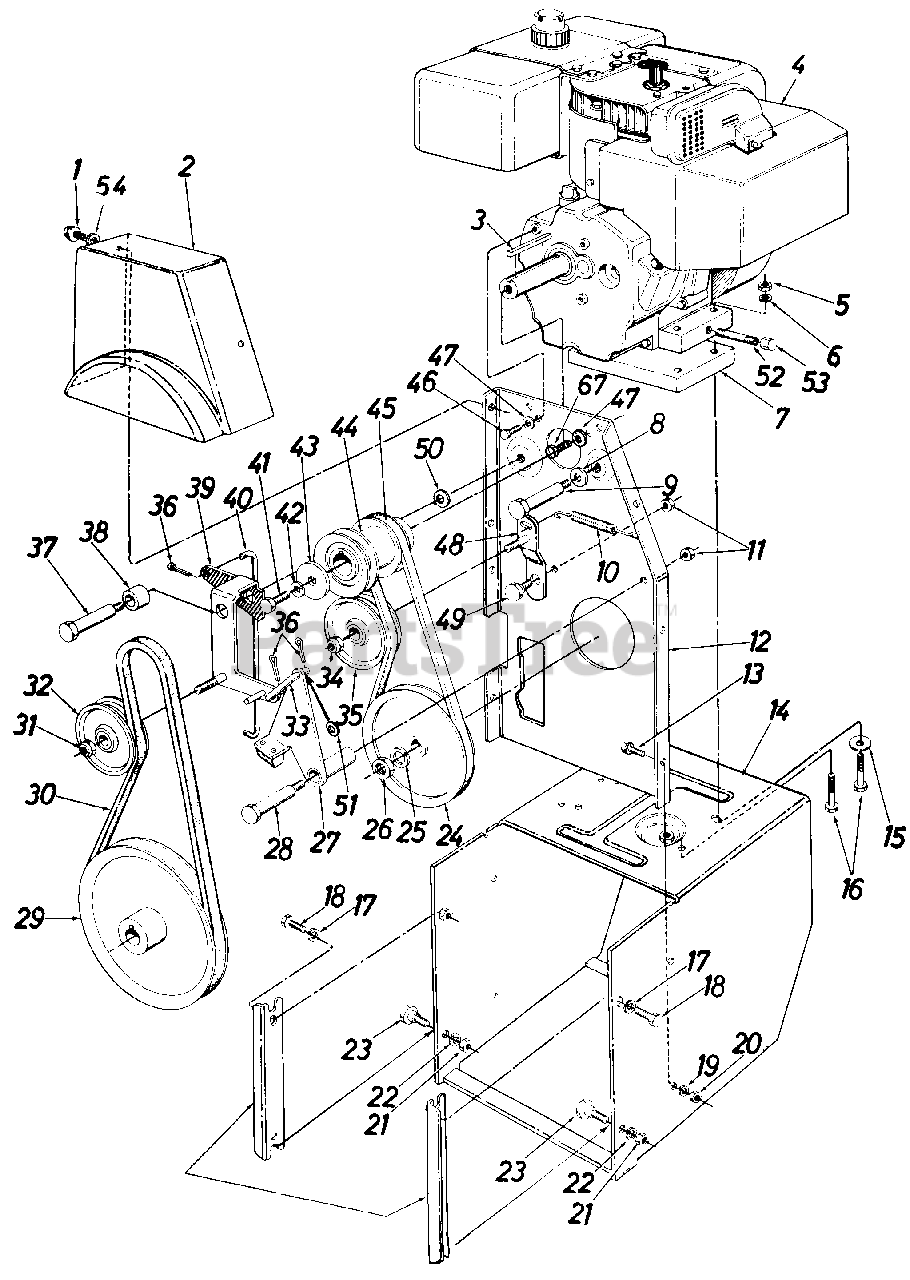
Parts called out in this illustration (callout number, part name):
1	Hex Wash. Self-Tap Scr. 5/16-24 x .50" Lg.
2	Belt Cover
3	Sq. Key 1/4" x 1.50" Lg.
4	Engine
5	Hex Nut 5/16-18 Thd.
6	L-Wash. 5/16" Scr.
7	Engine Spacer Ass'y.
8	Bell-Wash. .40 I.D. x .88 0. D
9	Shld. Scr. .498" Dia. x 3.00" Lg.
10	Ext Spring .38 O.D. x 3.18" Lg.
11	Hex Cent. L-Nut 3/8-16 Thd.
12	Engine Brkt. Ass'y.
13	Hex Sems Scr. 5/16-18 x .75" Lg.
14	Frame Ass'y.
15	Fl-Wash. .345 I.D. x .75 O.D. x .060
16	Hex Scr. 5/16-18 x 2.50" Lg.
17	L-Wash. 3/8" Scr. H.D.
18	Pilot Scr. 3/8-16 x .88" Lg.
19	L-Wash. 5/16" Scr.
20	Hex Nut 5/16-18 Thd.
21	Hex Nut 3/8-16 Thd.*
22	L-Wash. 3/8" Scr. H.D.
23	Shld. Scr. .498" Dia. x .340" Lg.
24	V-Puiley .628 I.D. x 7.50 O.D.
25	L-Wash. for 5/8" Scr.
26	Hex Ins. Jam L-Nut 5/8-18 Thd.
27	Brake Brkt. Ass'y.
28	Shld. Scr. .498" Dia. x 2.00" Lg.
29	V-Pulley .875 I.D. x 10.12 O.D.
30	"V"-Belt
31	Hex Ins. Jam L-Nut 3/8-24 Thd.
32	Fl-Idler w/Flanges 3.0 O.D.
33	Brake Linkage Ass'y.
34	Hex Ins. Jam L-Nut 3/8-24 Thd.
35	3.0" O.D. Fl-Idler w/Flanges
36	Int. Cot. Pin 5/16" Dia.
37	Shld. Scr. .625 Dia. x 2.750" Lg.
38	Spacer .75 O.D. x 1.00" Lg.
41	Hex Bolt 3/8-24 x 1.25" Lg.
42	L-Wash. 3/8" Scr. H.D.
43	Fl-Wash.
44	Engine Pulley-Double Groove
45	"V"-Belt
46	Hex Scr. 5/16-24 x .62" Lg.
47	Bell-Wash. .345 I.D. x .88 O.D. x .060
48	Drive Idler Brkt. Ass'y.
49	Shld. Scr.-.625" Dia. x . 170" Lg.
50	Bell-Wash. .40 I.D. x 1.12 O.D.
51	Fl-Wash. .34 I.D. x .750 O.D. x .05
52	Pipe Nipple-1/2" Pipe Thd. x 3.00" Lg.
53	Hex Scr. 1/4-18 Pipe Thd.
54	Fl-Wash. .340 I.D. x .62 O.D. x .62
